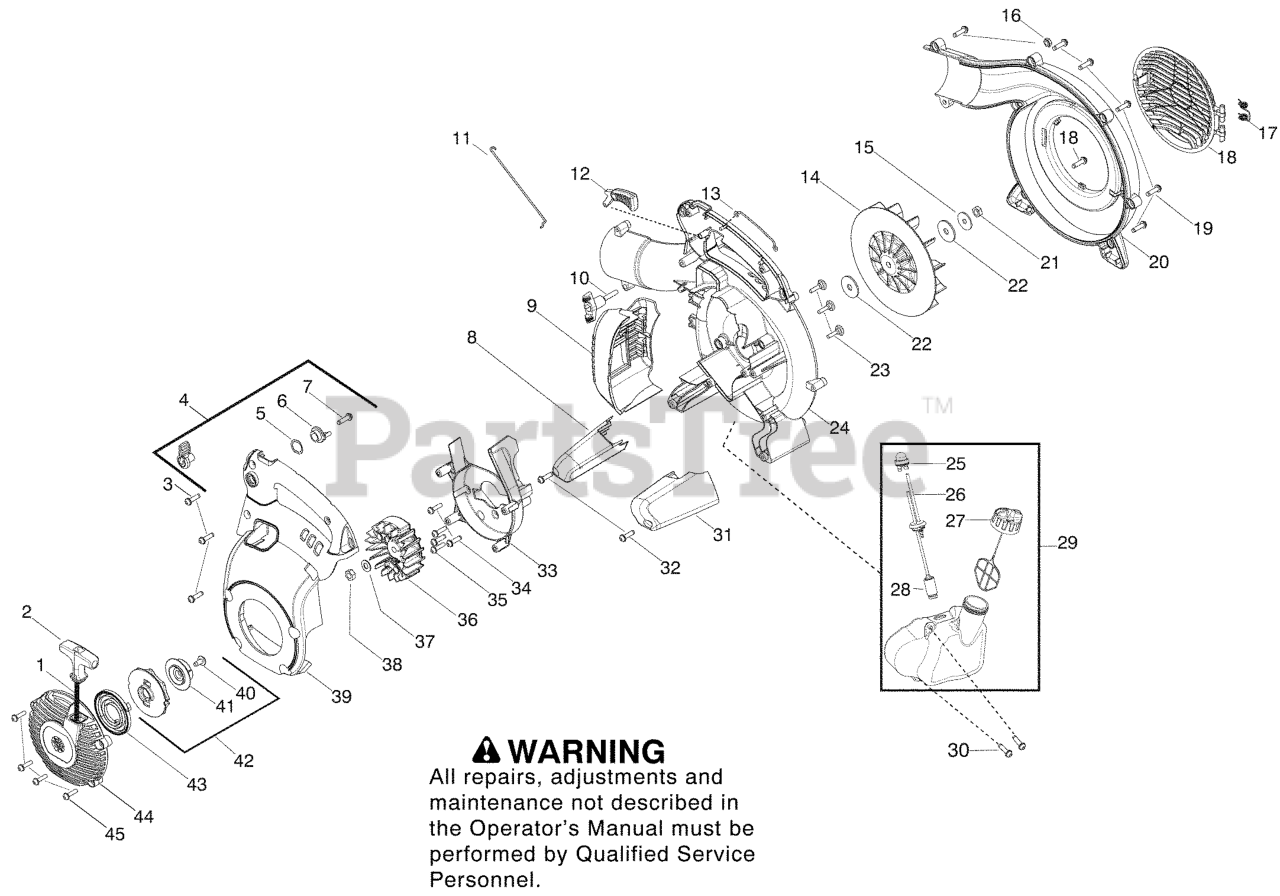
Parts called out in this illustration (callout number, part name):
2	STARTER HANDLE
4	KIT CRUISE CONTROL
5	WAVE WASHER
6	RATCHET CRUISE CONTROL
8	FOOT, FRONT IMPACT
9	ASSY, MUFFLER GUARD
10	ASSY, BLOWER KNOB
11	WIRE LINKAGE
12	TRIGGER, THROTTLE
13	WIRE, HANDLE GROUND
14	IMPELLER
15	WASHER-FLYWHEEL
17	SPRING, VAC DOOR
18	COVER VAC DOOR
20	ASSY, OUTER SCROLL
21	NUT, IMPELLER
22	WASHER IMPELLER
23	SCREW FUEL TANK RETAINER
24	SCROLL, INNER
26	KIT FUEL LINE GROMMET
27	ASSY-CAP W/RETAINER
28	FUEL PICK-UP ASSY
29	ASSY, FUEL TANK
31	FOOT, REAR IMPACT
33	Scroll - Flywheel
35	SCREW - SHROUD
36	ASSY, FLYWHEEL
37	WASHER FLAT
38	NUT-FLYWHEEL
39	COVER, MOTOR HOUSING
42	KIT - STARTER
43	SPRING STARTER
44	HOUSING - STARTER COVER
45	SCREW - SHROUD
